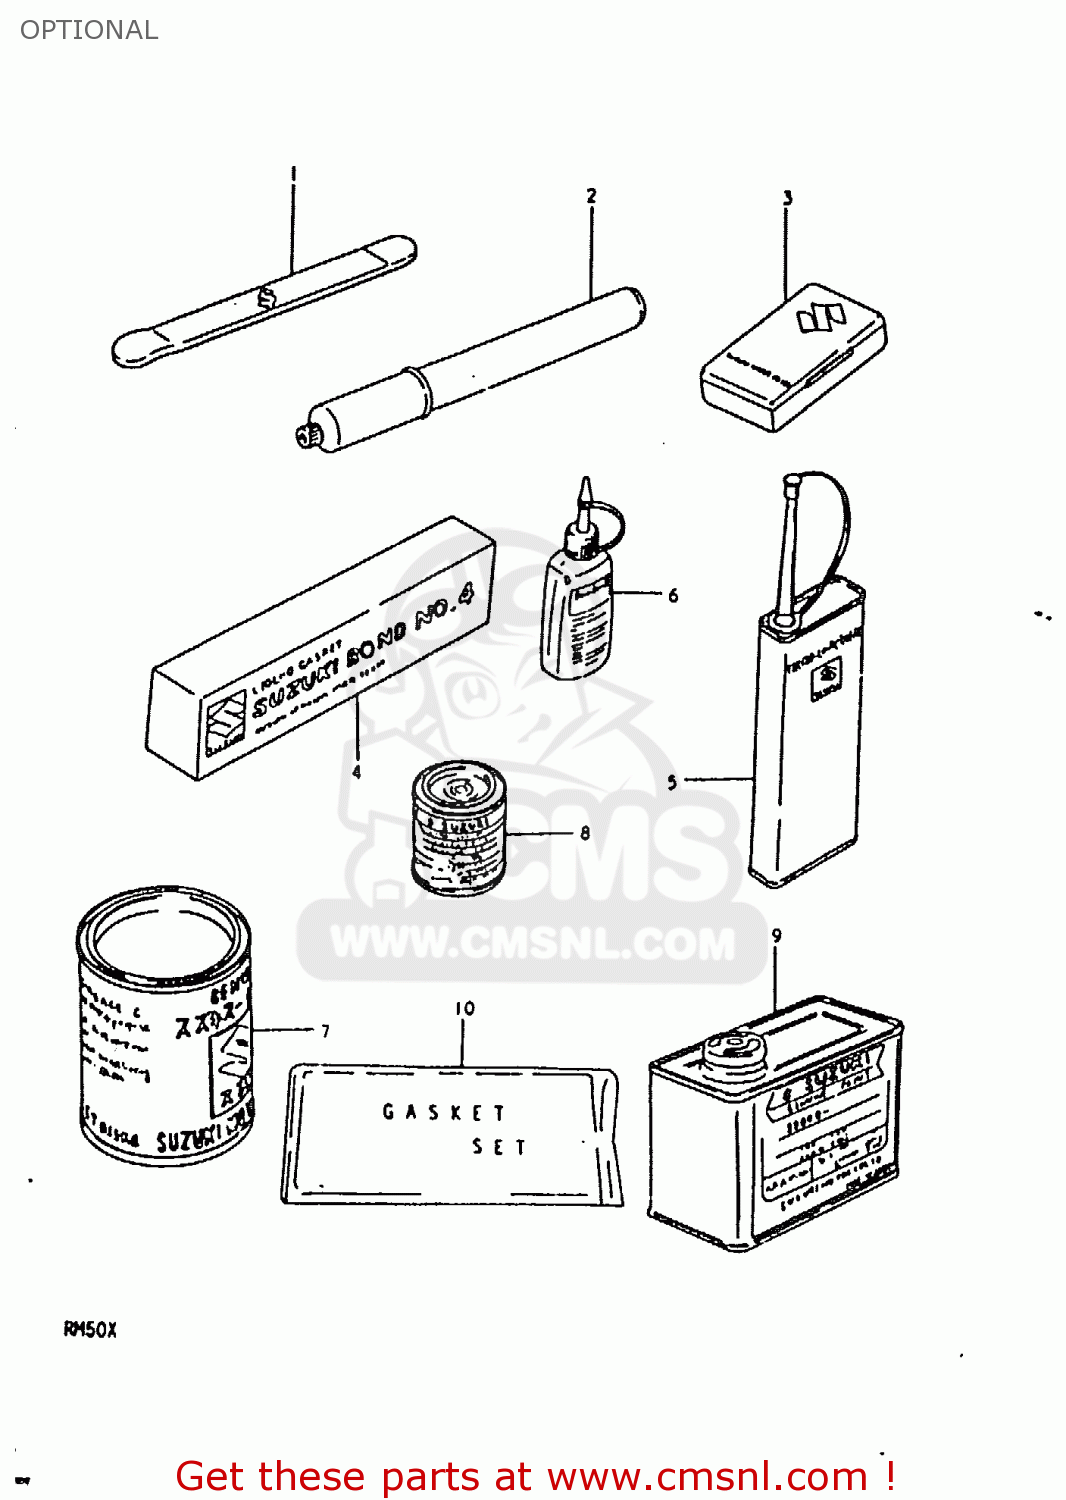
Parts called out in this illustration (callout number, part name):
1	LEVER,TIRE
2	INFLATOR, AIR
3	TUBE REPARING TOOL
4	BOND 1104
5	THREAD LOCK NO.1401 CLEAR 200G
6	THREAD LOCK NO.1303B PURPL 50G
7	GREASE(C)EP2 LITHIUM 150G
8	PAINT,BLACK
9	PAINT (BLACK)
10	GASKET SET (NAS)
